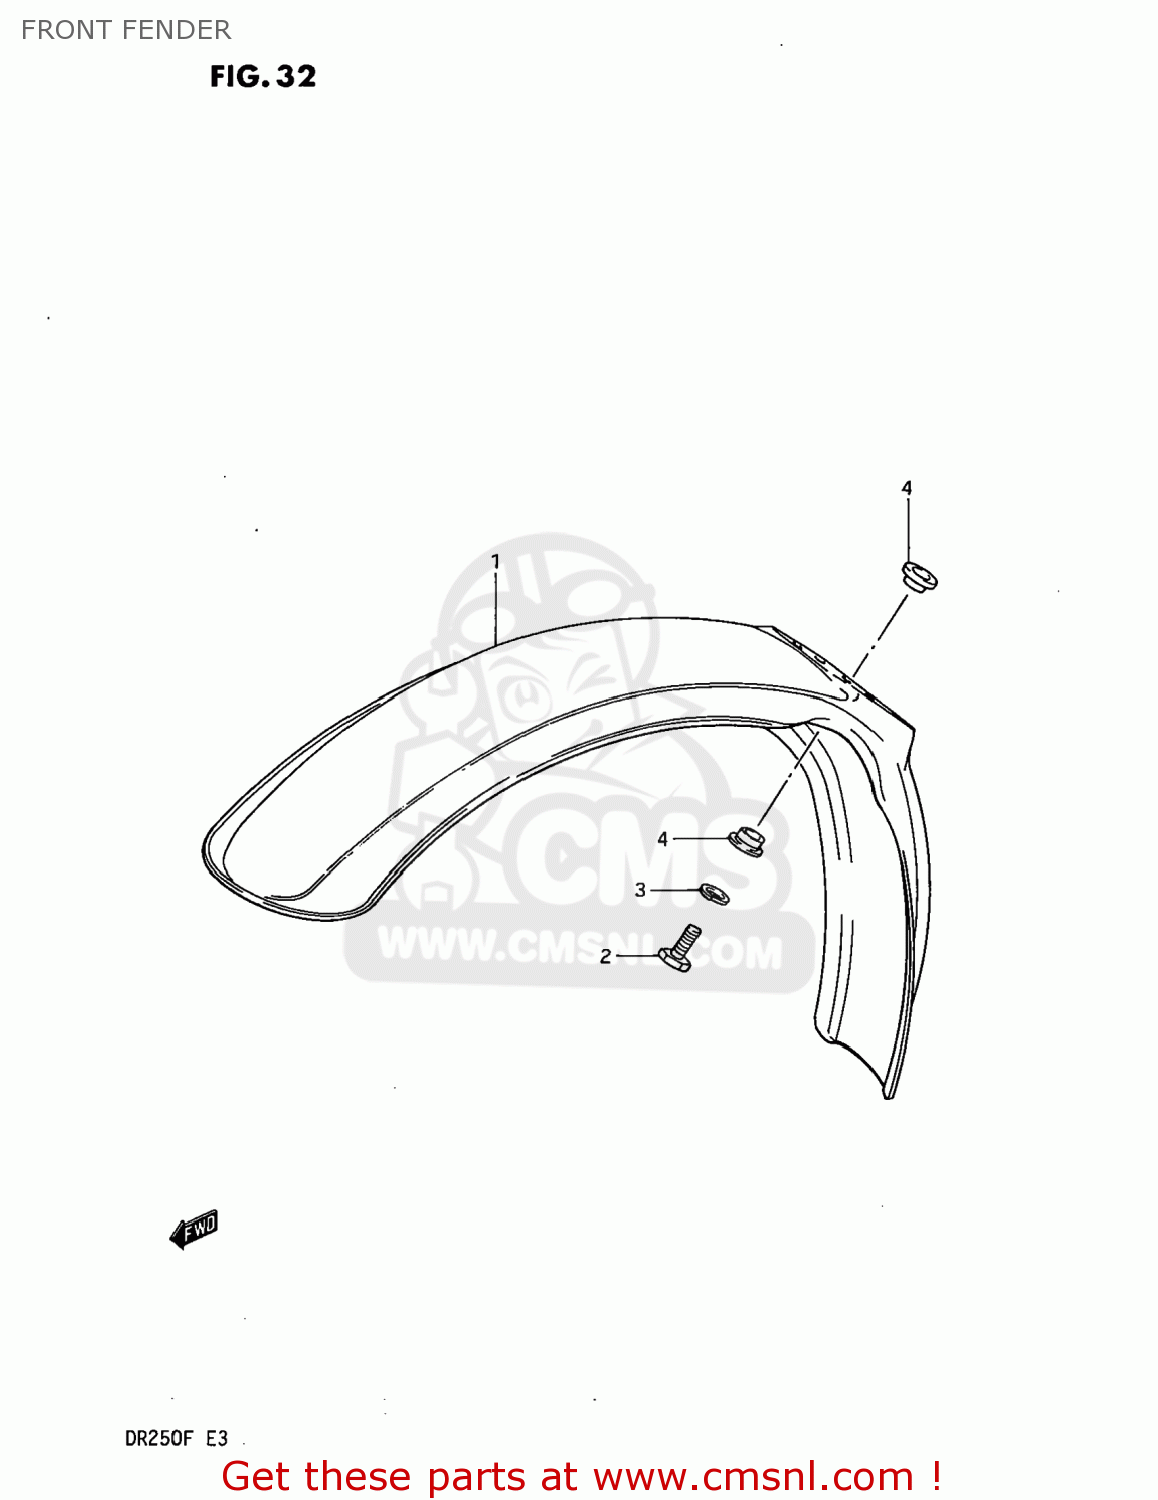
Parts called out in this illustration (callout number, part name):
1	FENDER,FRONT
2	BOLT, UPPER
3	WASHER,LOCK
4	SPACER
